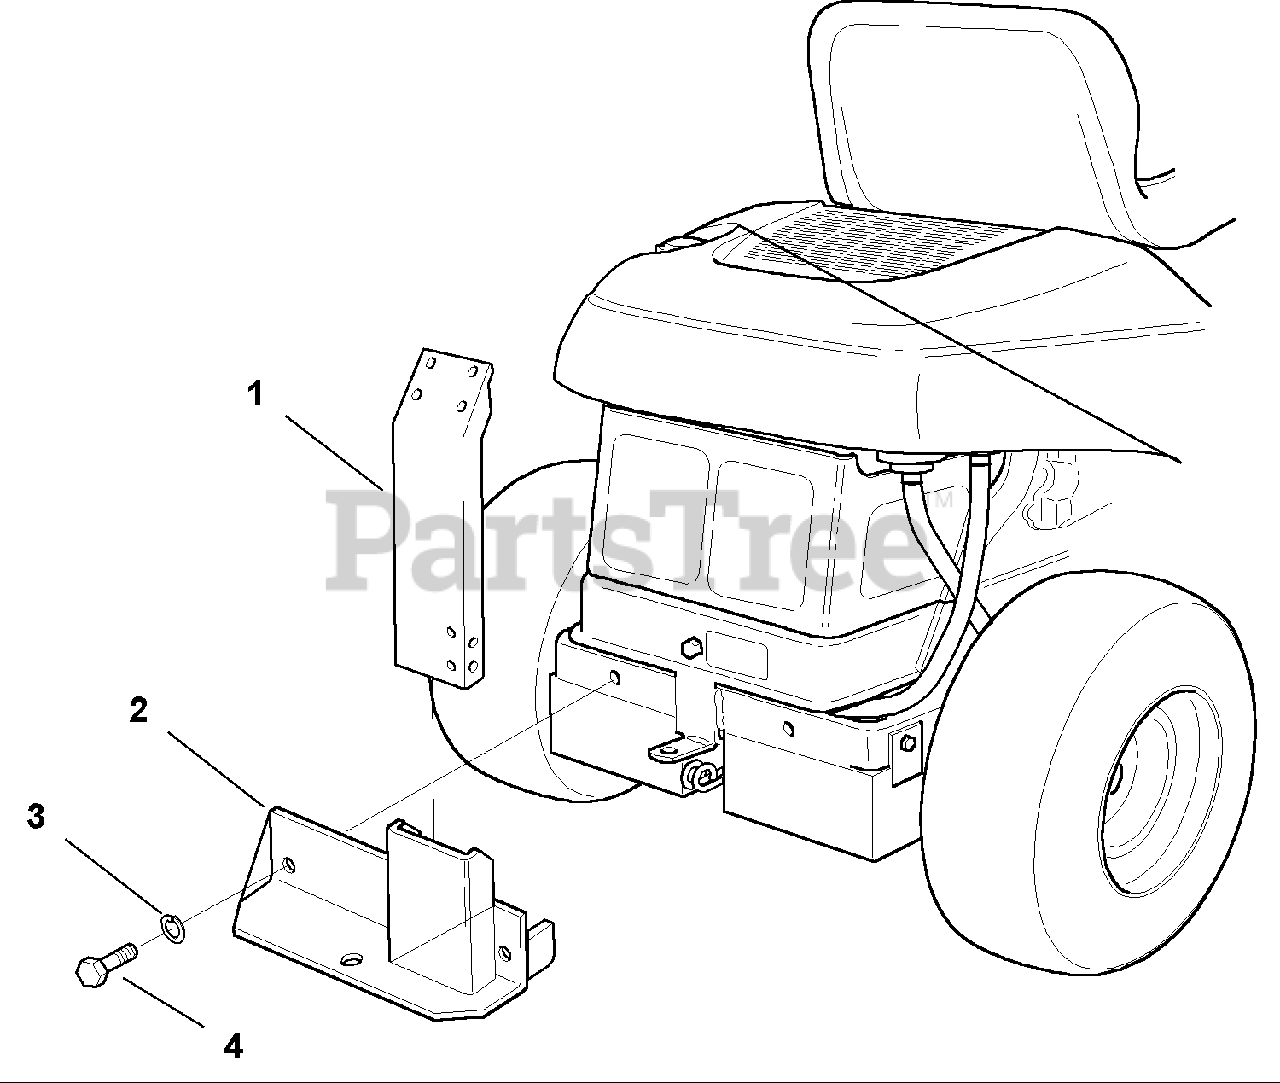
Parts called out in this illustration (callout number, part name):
1	SUPPORT, Upright
2	HITCH & CHANNEL ASSEMBLY
3	LOCKWASHER, 3/8
4	CAPSCREW, Hex Head, 3/8-16 x 4 Gr. 8
4	CAPSCREW, Hex Head, 3/8-16 x 3 Gr. 8 Use on 1996 & 1997 Products
